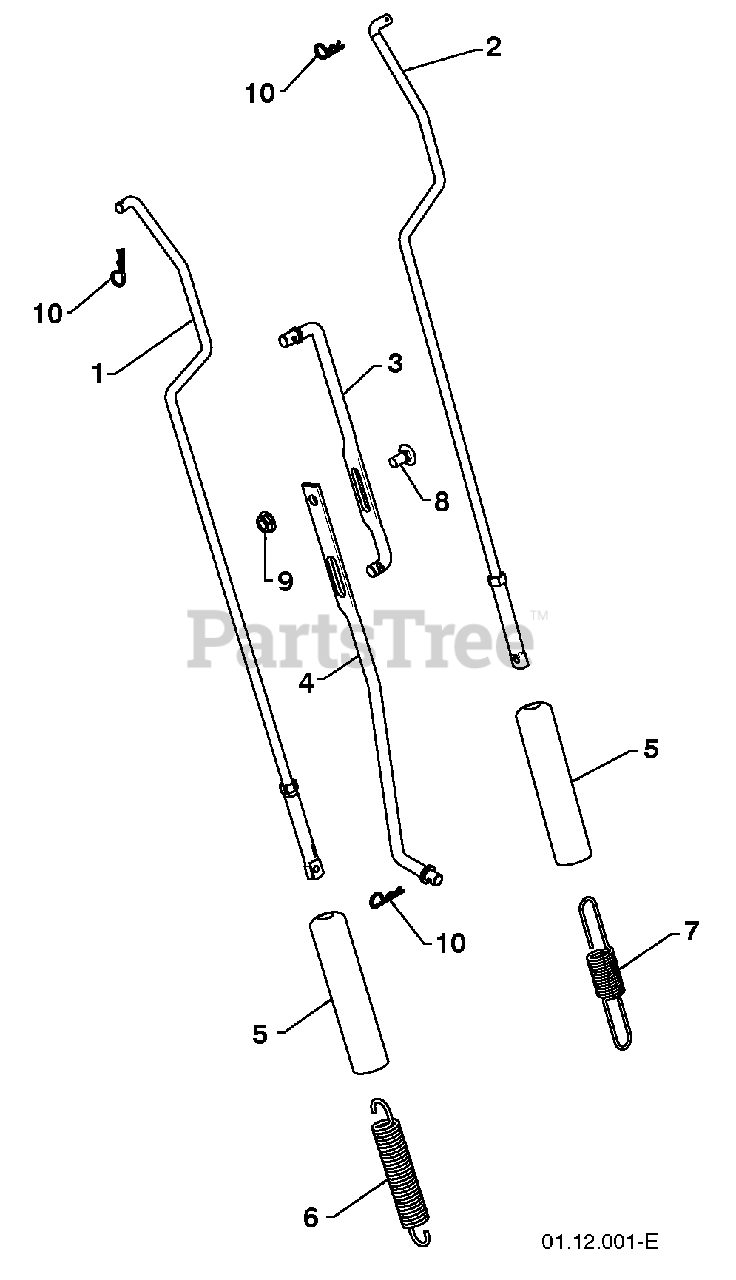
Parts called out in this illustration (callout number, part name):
1	IMPELLER ROD ASSEMBLY
2	TRACTION ROD ASSEMBLY
3	SHIFTER ROD TOP
4	SHIFTER ROD BOTTOM
5	SPRING SLEEVE
6	IMPELLER SPRING
7	TRACTION SPRING
8	CARRIAGE BOLT 5/16-18 X .75
9	NUT 5/16-18
